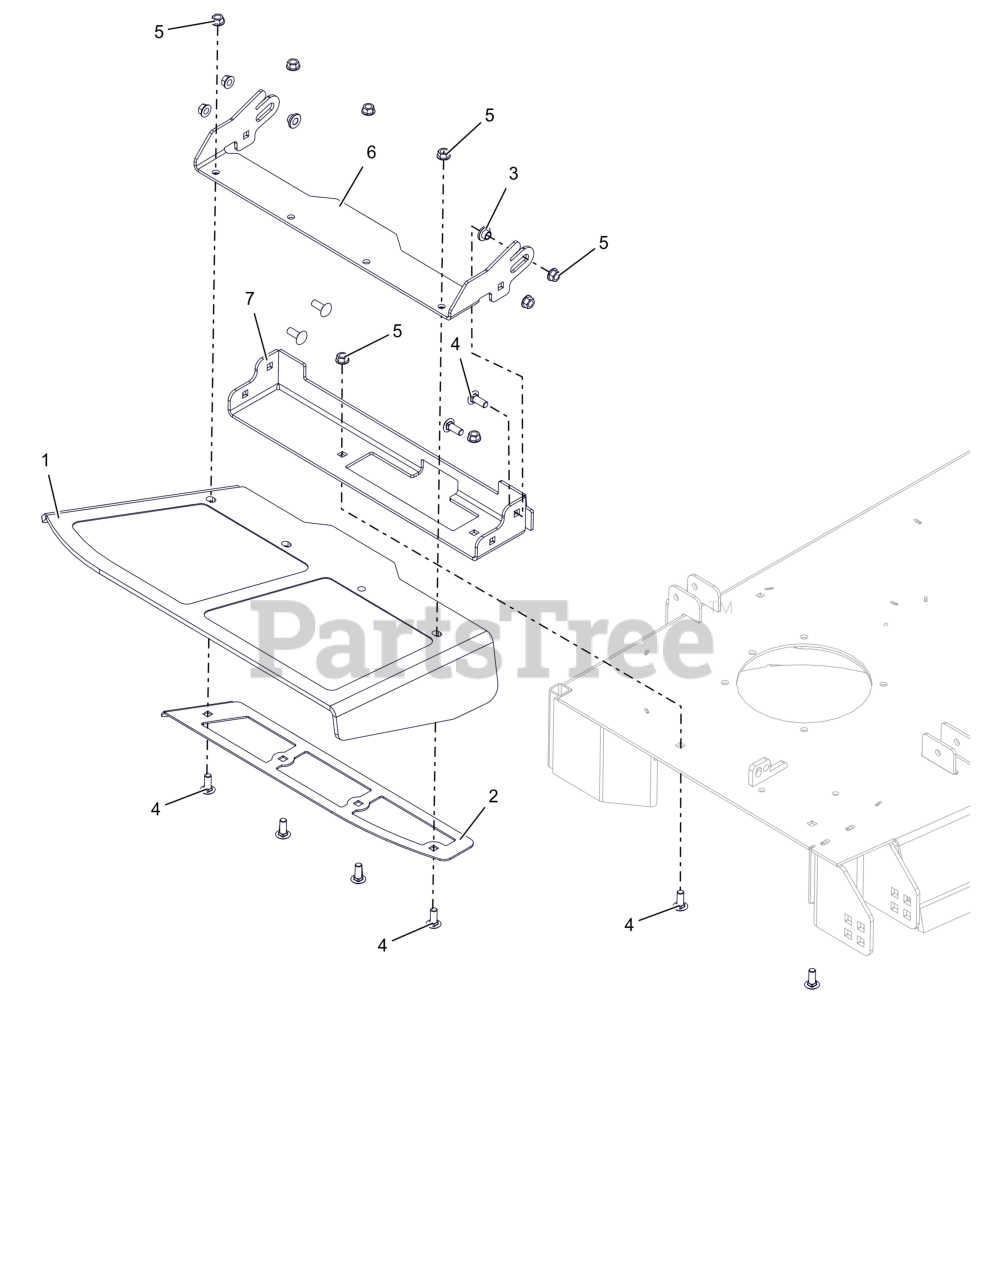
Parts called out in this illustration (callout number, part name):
1	CHUTE, FORMED RUBBER DISCHARGE
2	PLATE- DISCH CHUTE CLAMP
3	BSHG-FLG .385X.500X.875X.406
4	BLT,RHSSN .38-16X1.00 G5 ZCC
5	NUT-LK-CTR-FLG .375-16 GF ZCC
6	BRKT, CHUTE MTG (ORANGE)
7	KIT-DISCH CHUTE LG ORG W/DECAL
